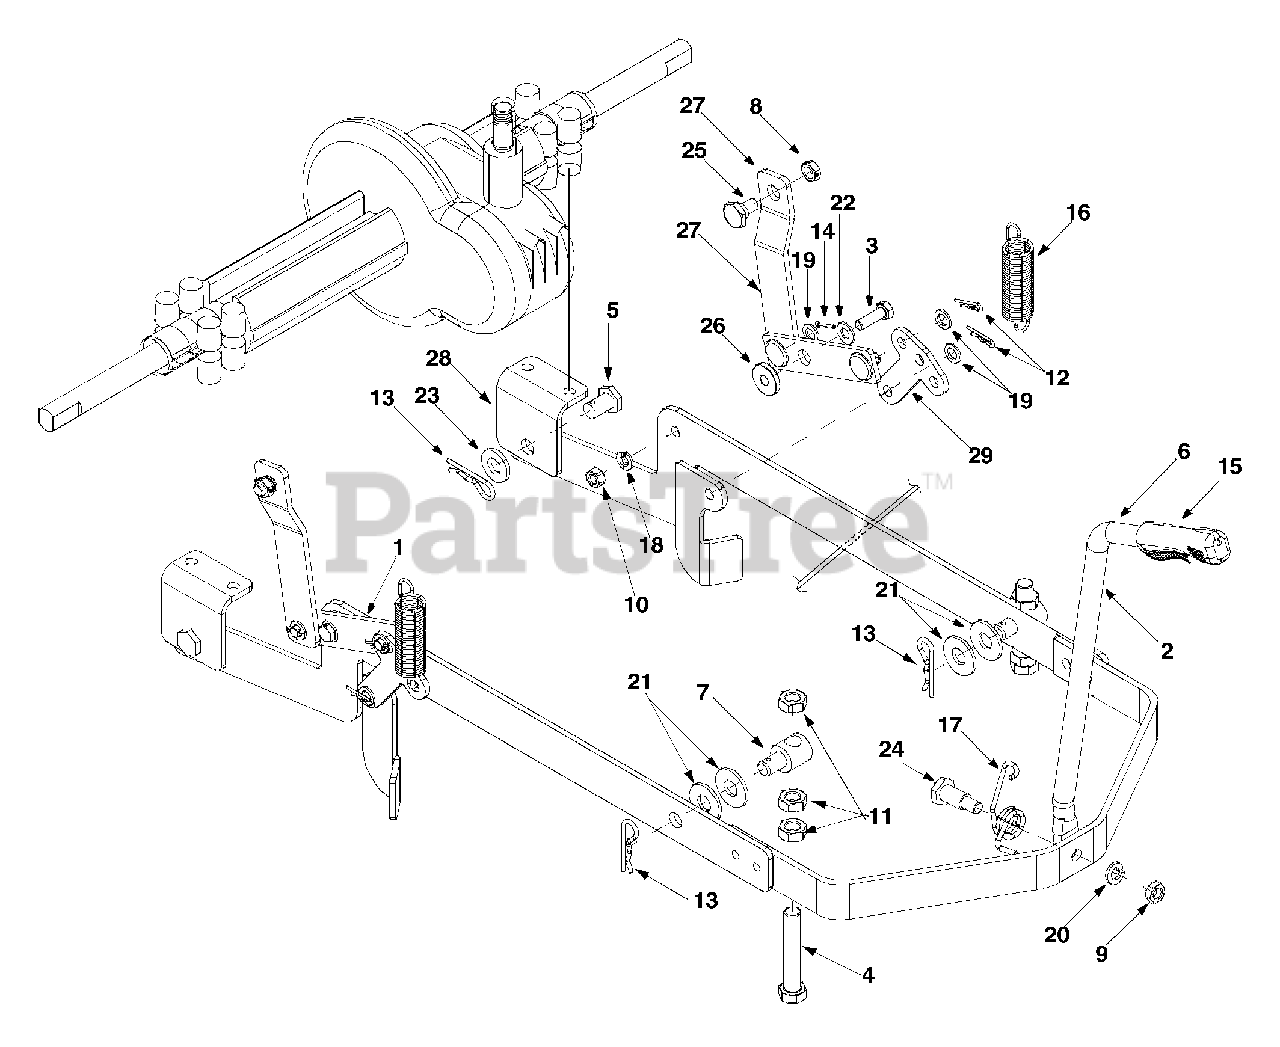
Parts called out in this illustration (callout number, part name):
3	Hex Screw 5/16-18 X 1.00 Gr.5
4	Hex Bolt 1/2-13 X 2.75 Gr.5 Spec.
5	Lift Bracket Pin
7	Ferrule
8	Jam Nut
9	Jam Nut 3/8-16 Gr. 5
10	Hex Nut 5/16-18
16	Extension Spring
17	Torsion Spring
18	Lock Washer 5/16
19	Flat Washer .385 x .620
21	Flat Washer
22	Flat Washer 5/16
24	Shoulder Screw
25	Shoulder Screw
26	Shoulder Spacer
